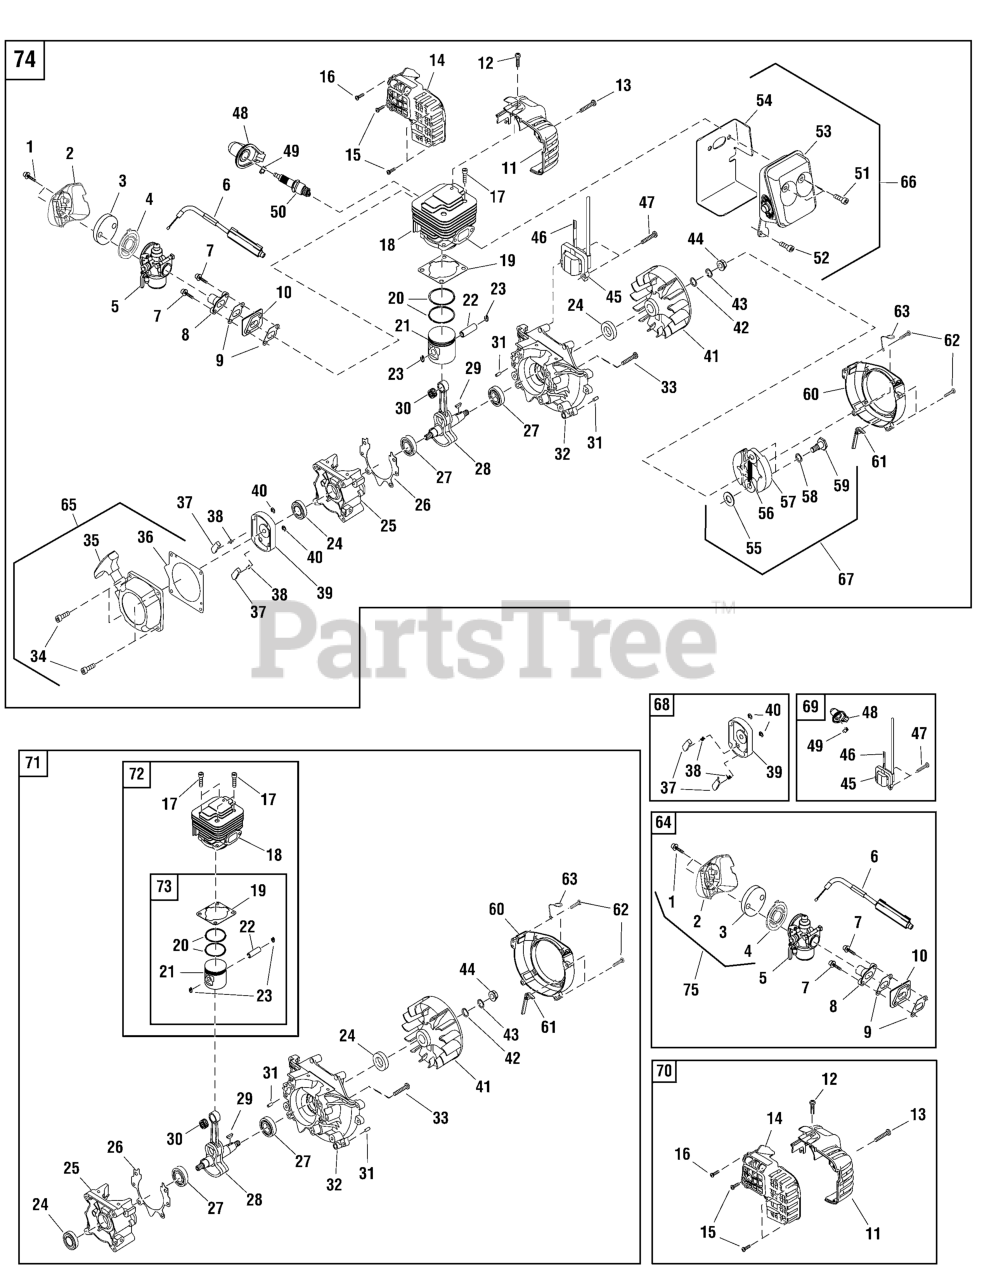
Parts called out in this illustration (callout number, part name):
1	BOLT, M4 x 25
2	COVER, Cleaner, Outer
3	FILTER
4	BRACKET, Filter Net
5	CARBURETOR, Ruixing
6	FUEL CABLE ASSEMBLY
7	BOLT, M5 x 25
8	ADMITTING PIPE
9	GASKET, Admitting Pipe
10	GASKET
11	SHROUD, Front
14	SHROUD, Back
15	SCREW, Self Tapping, 5 x 20
16	SCREW, Self Tapping, 4.2 x 30
17	BOLT, M5 x 18
18	CYLINDER
19	GASKET, Cylinder
20	RING, Piston
21	PISTON
22	PIN, Piston
23	RING, Pin Retain
24	SEAL, Oil, 11.7 x 22 x 7
25	CRANK CASE, Rear
26	GASKET, Crank Case
27	BEARING, 6201/P6
28	CRANKSHAFT
29	KEY, 3 x 5 x 13
30	BEARING, Needle
31	PIN, Cylindrical, B4 x 10
32	CRANK CASE, Front
35	KIT, Shroud Assembly
36	STARTER PAD
37	STARTER CINCH
38	SPRING, Starter
39	STARTER BOX
40	RING, Retainer
41	FLY WHEEL
42	WASHER, Flat, Dia. 8
43	WASHER, Spring, Dia. 8
44	NUT, M8
45	MAGNETO COIL
46	CORD, Magneto
48	BOOT, Spark Plug
49	CLIP, Spark Plug
50	SPARK PLUG
53	MUFFLER
54	GASKET, Muffler
55	WASHER, B
56	SPRING, Clutch
57	EXPANDER, Complete
58	WASHER, Wave
59	SCREW, Shaft
60	COVER, Fan
61	FLASH PAN
63	BRACKET
64	KIT, Air Cleaner & Carburetor
65	KIT, Starter Assembly
66	KIT, Muffler Assembly
67	KIT, Expander Assembly
68	KIT, Start Reel Assembly
69	KIT, Magneto Assembly
70	KIT, Shroud Assembly
71	KIT, Cylinder Assembly
72	KIT, Cylinder Head
73	KIT, Piston
74	ENGINE ASSEMBLY, Complete
75	KIT, Air Cleaner
